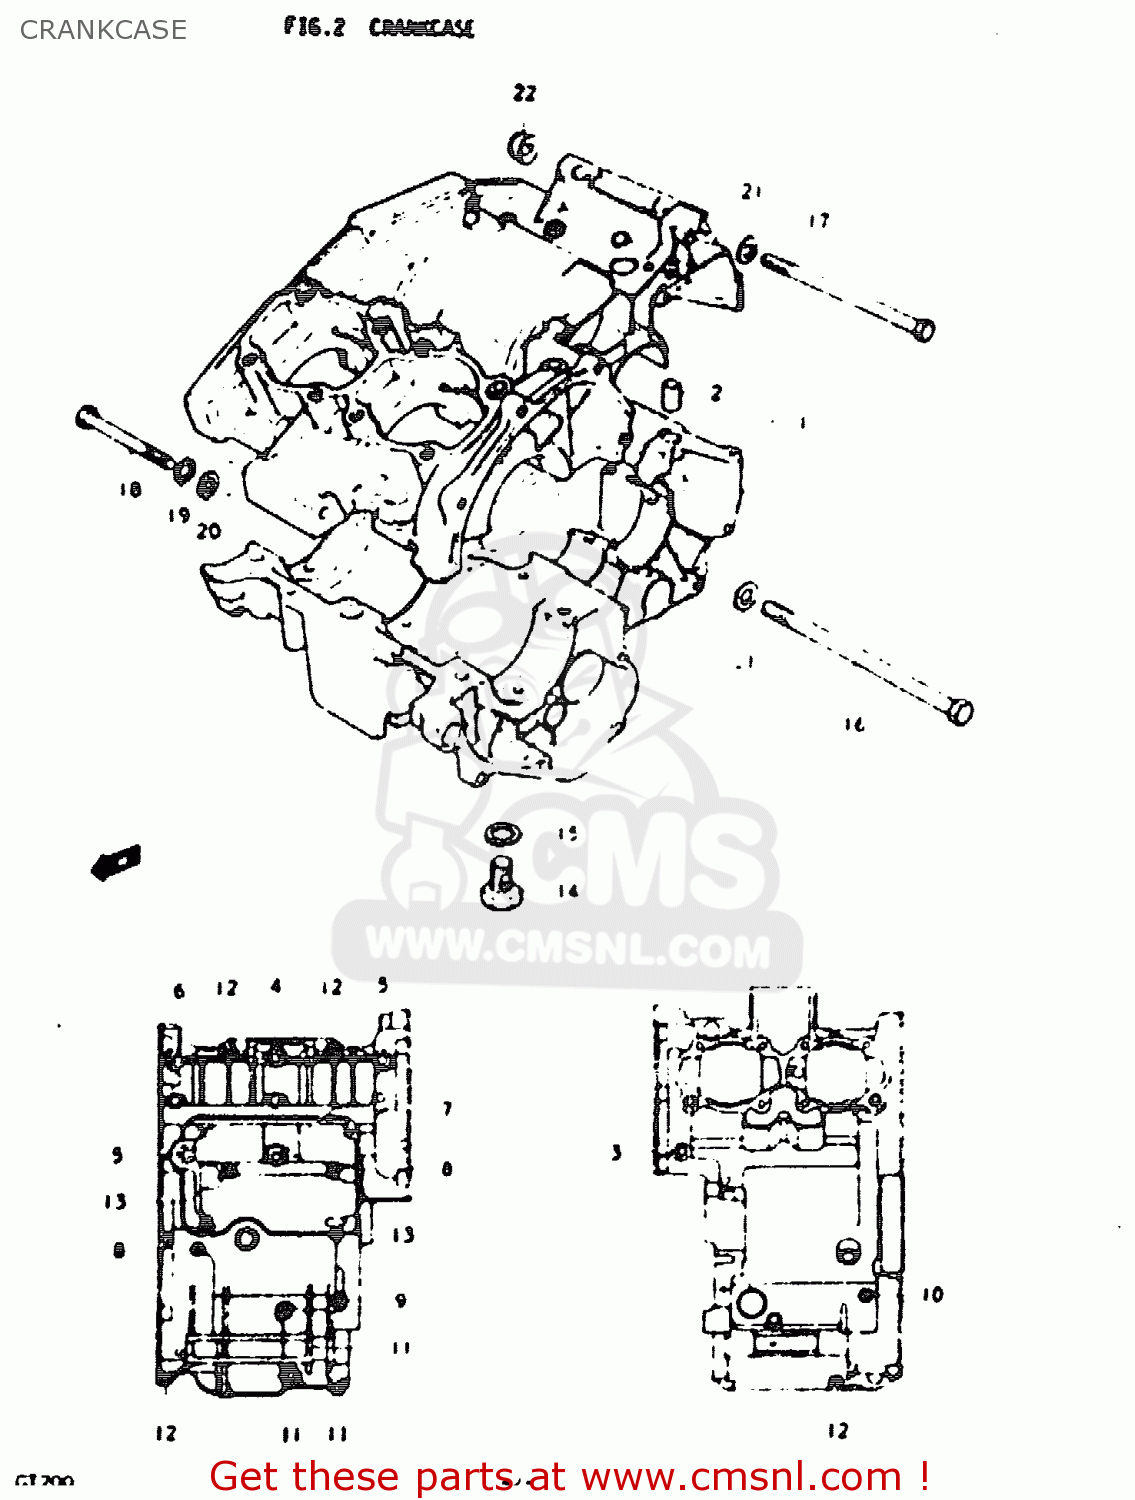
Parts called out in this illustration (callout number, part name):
1	CRANKCASE SET
2	PIN
3	BOLT
4	BOLT 8X75
5	BOLT 6X65
6	BOLT 8X55
7	BOLT
8	BOLT (6X90)
9	BOLT (6X80)
10	BOLT 6X65
11	BOLT (6X60)
12	BOLT ,6X50
13	BOLT
14	PLUG
15	GASKET(14X19.2X2) (NAS)
16	BOLT
17	BOLT, ENGINE MOUNTING NO.2
18	BOLT,8X75
19	WASHER,LOCK,8.
20	WASHER
21	WASHER
22	NUT
